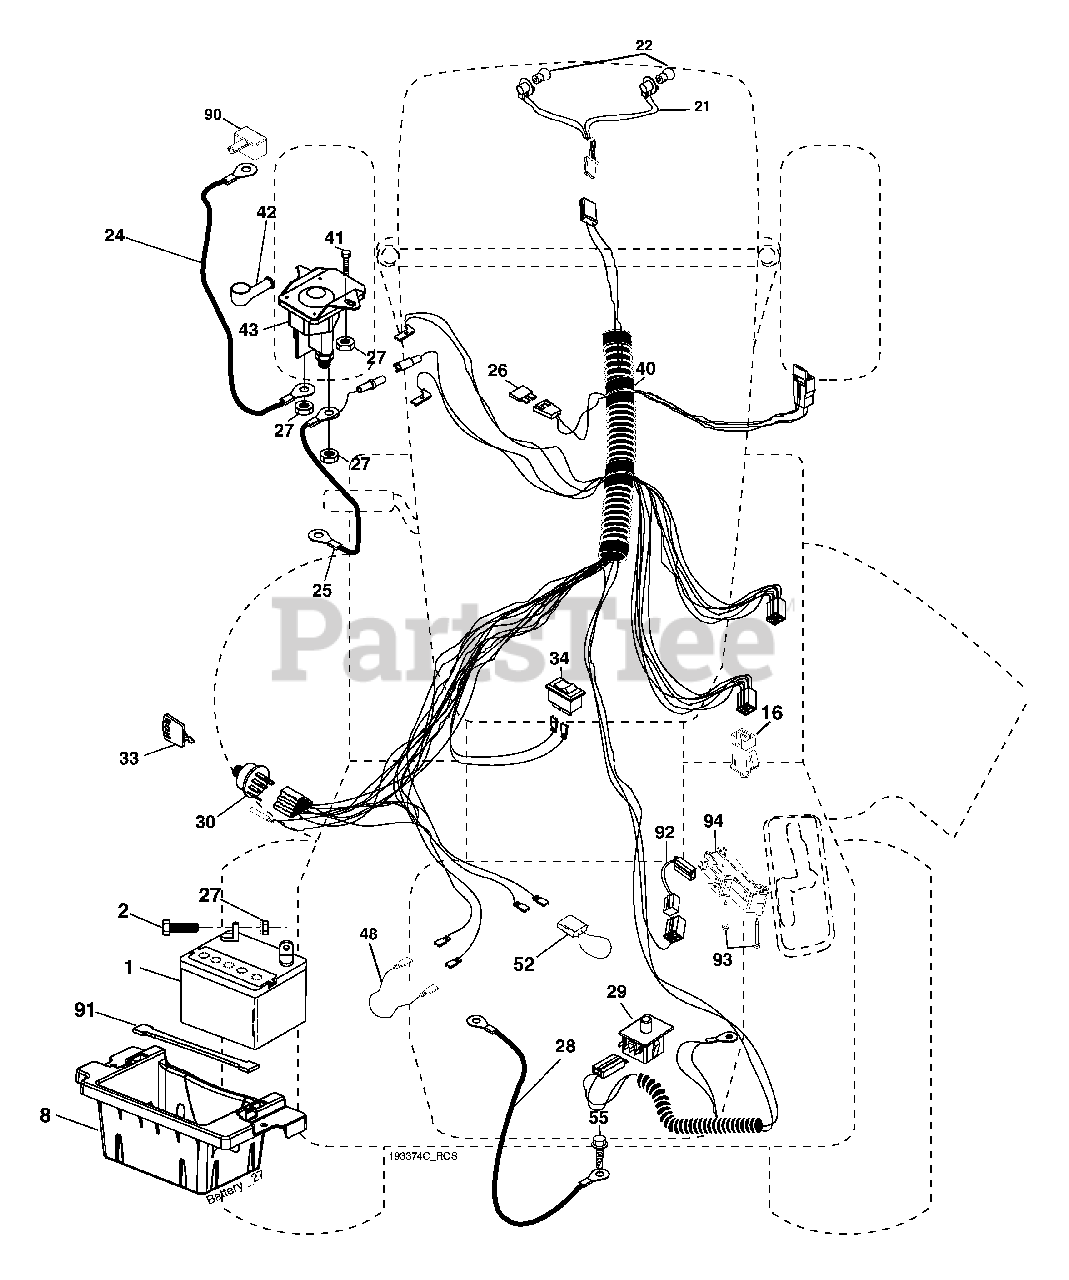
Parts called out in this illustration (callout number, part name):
1	Battery
2	Bolt Hex Hd 1/4-20 unc x 3/4
8	Box Battery
16	Switch Interlock
21	Harness Socket Light
22	Bulb, Light # 1156
24	Cable Battery
25	Cable Battery 6 Ga. Red w/16 wire
26	Fuse
27	Nut Keps Hex 1/4-20 unc
28	Cable Ground 21" Blk 6 Ga.
29	Switch Seat
30	Switch Ign
33	Key Ign Molded Generic
34	Switch Light/Reset
40	Harness Ign
41	Bolt Fin Hex 1/4-20 unc x 1/2
42	Cover Terminal Red
43	Solenoid
48	Adapter Ameter
52	Protection Loop
55	Screw Thdrol 5/16-18 x 1/2
90	Cover Terminal
91	Strap Battery Mount Front
92	Harness Pigtail Reverse Switch
93	Screw Plastite 10-14 x 2.0
94	Module Revers ROS
